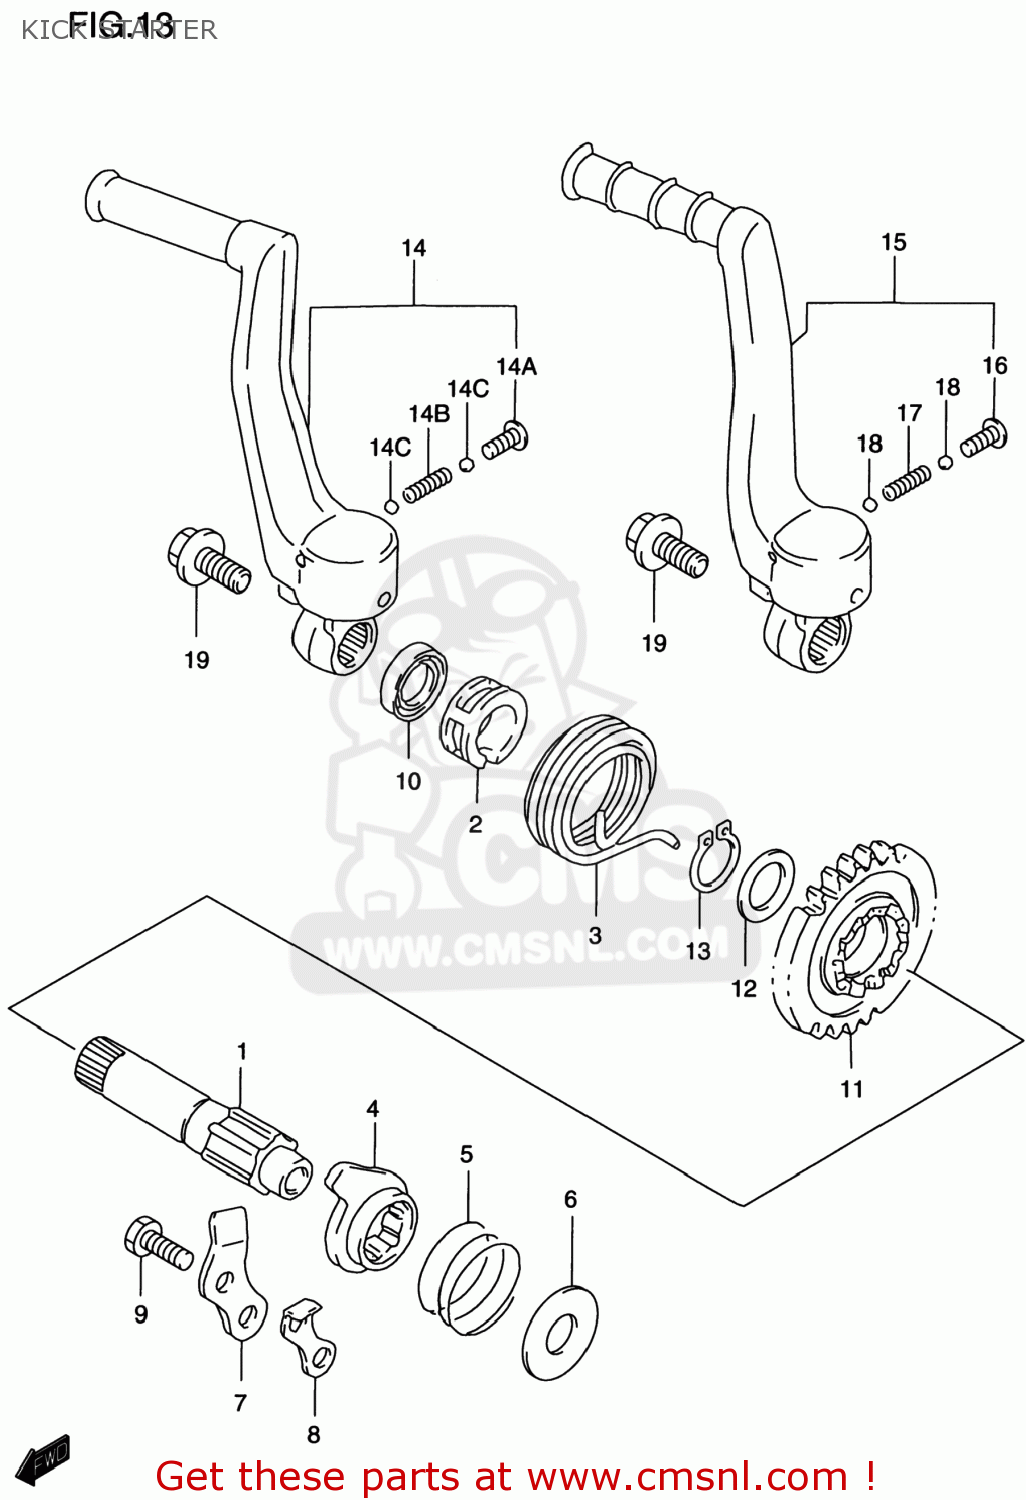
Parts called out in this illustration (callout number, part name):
1	SHAFT,KICK STARTER
2	GUIDE,KICK STARTER SFT SPRING
3	SPRING
4	STARTER,KICK
5	SPRING
6	WASHER
7	GUIDE,KICK STARTER
8	STOPPER,KICK STARTER
9	BOLT
10	SEAL,OIL(15.8X24X5)
11	GEAR,KICK STARTER DRIVE
12	WASHER
13	CIRCLIP 16MM
14	LEVER ASSEMBLY,KICK STARTER
14A	SCREW(6X27.5)
14B	SPRING
14C	BALL
15	LEVER ASSY,KICK STARTER
16	SCREW(6X27.5)
17	SPRING
18	BALL
19	BOLT(8X14)
